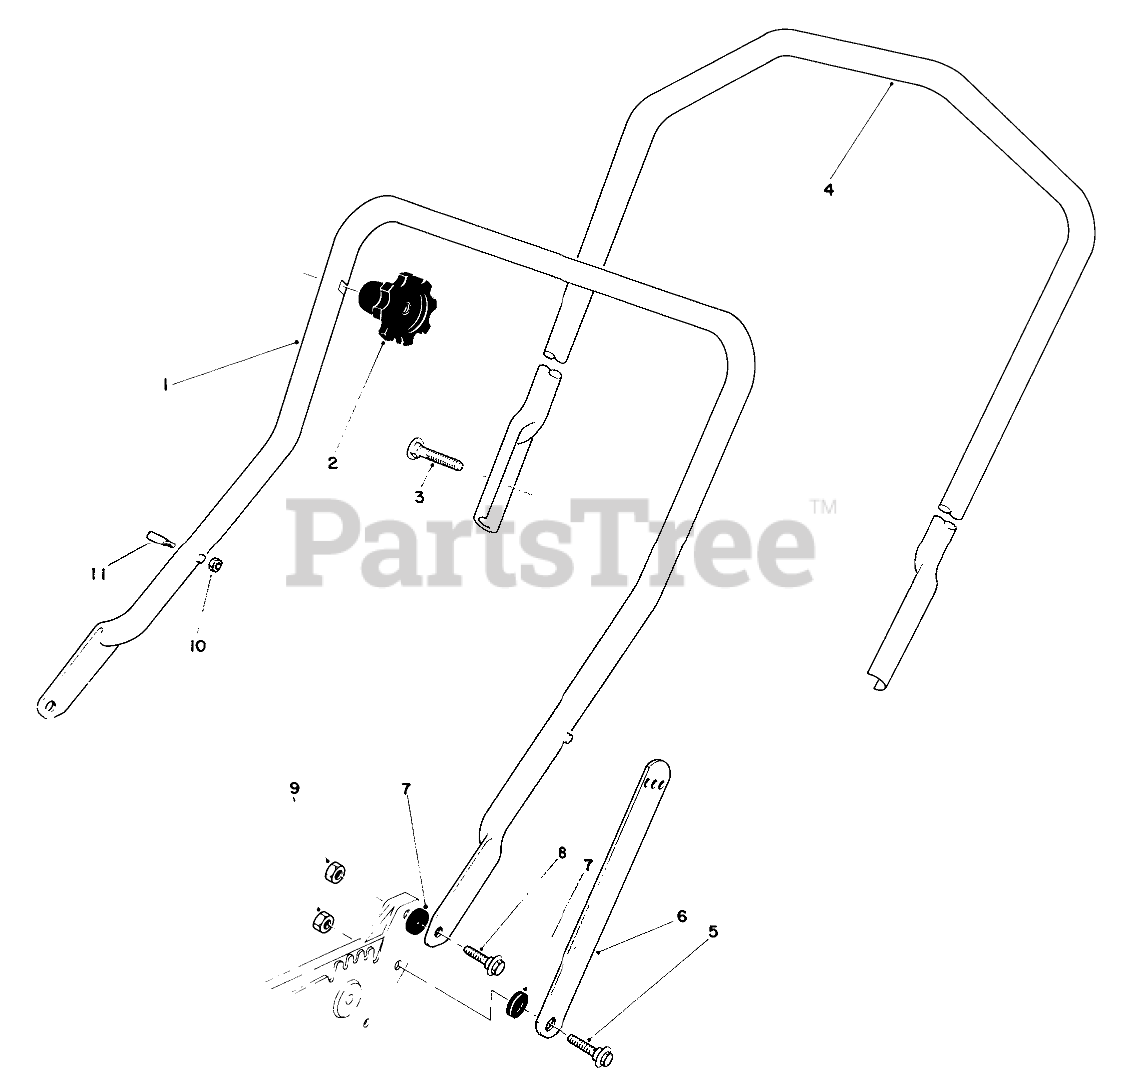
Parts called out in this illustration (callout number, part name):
1	Handle-Lower
3	5/16-18 X 2 HNDLE SCREW
4	Handle-Upper
5	SCREW-SHOULDER
6	Handle Latch
7	SPACER
8	SCREW-SHOULDER
9	NUT-LOCK, NI
10	NUT-LOCK, NI
11	HANDLE PIN
